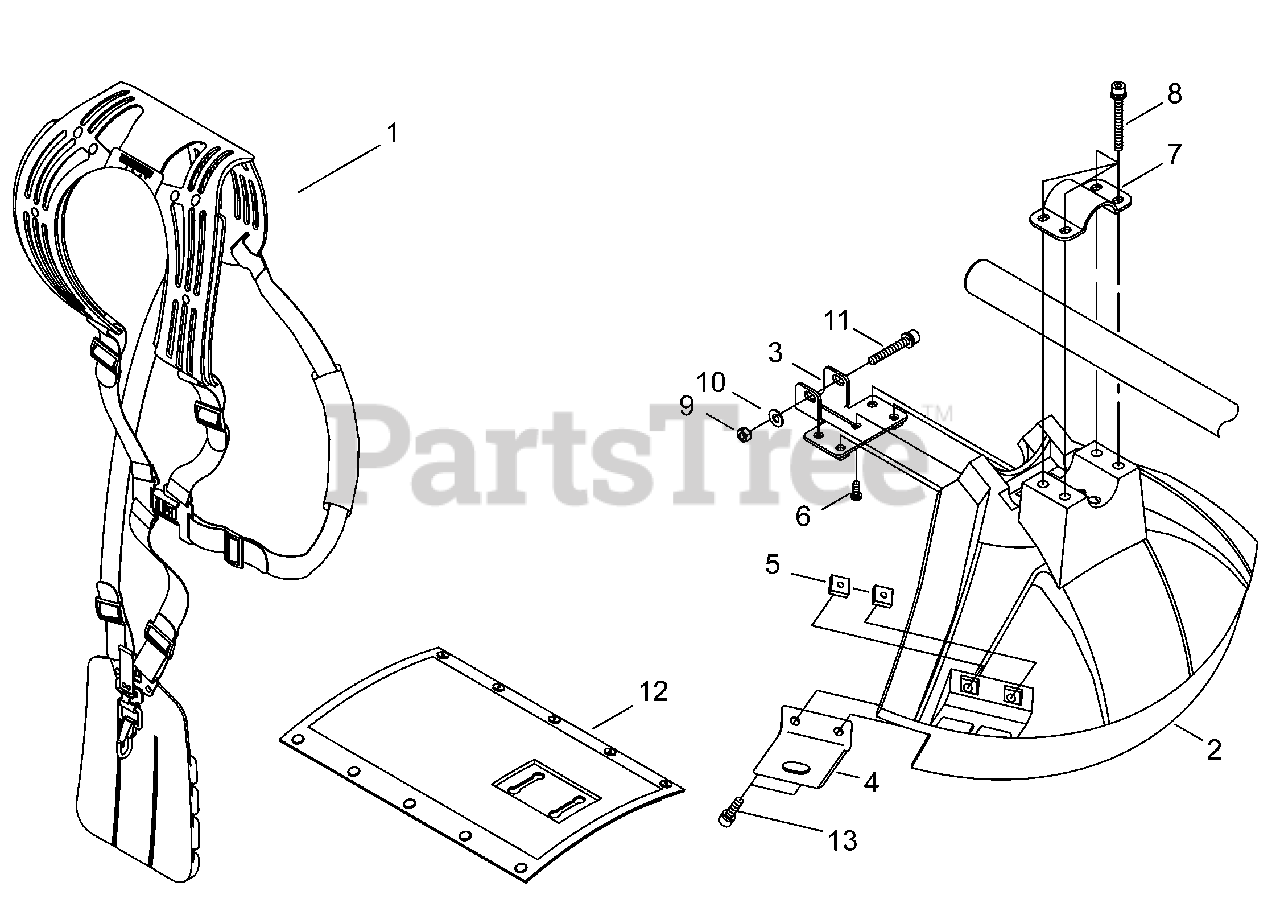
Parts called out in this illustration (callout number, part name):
1	HARNESS ASSY
2	SHIELD, DEBRIS
3	CLAMP, LOWER
4	CUTTER
5	NUT M5
6	SCREW HILO 4×10
7	CLAMP, UPPER
8	BOLT M5×45
9	NUT, HEX M6
10	WASHER
11	BOLT M6×40
12	PROTECTOR
13	BOLT M5×16
